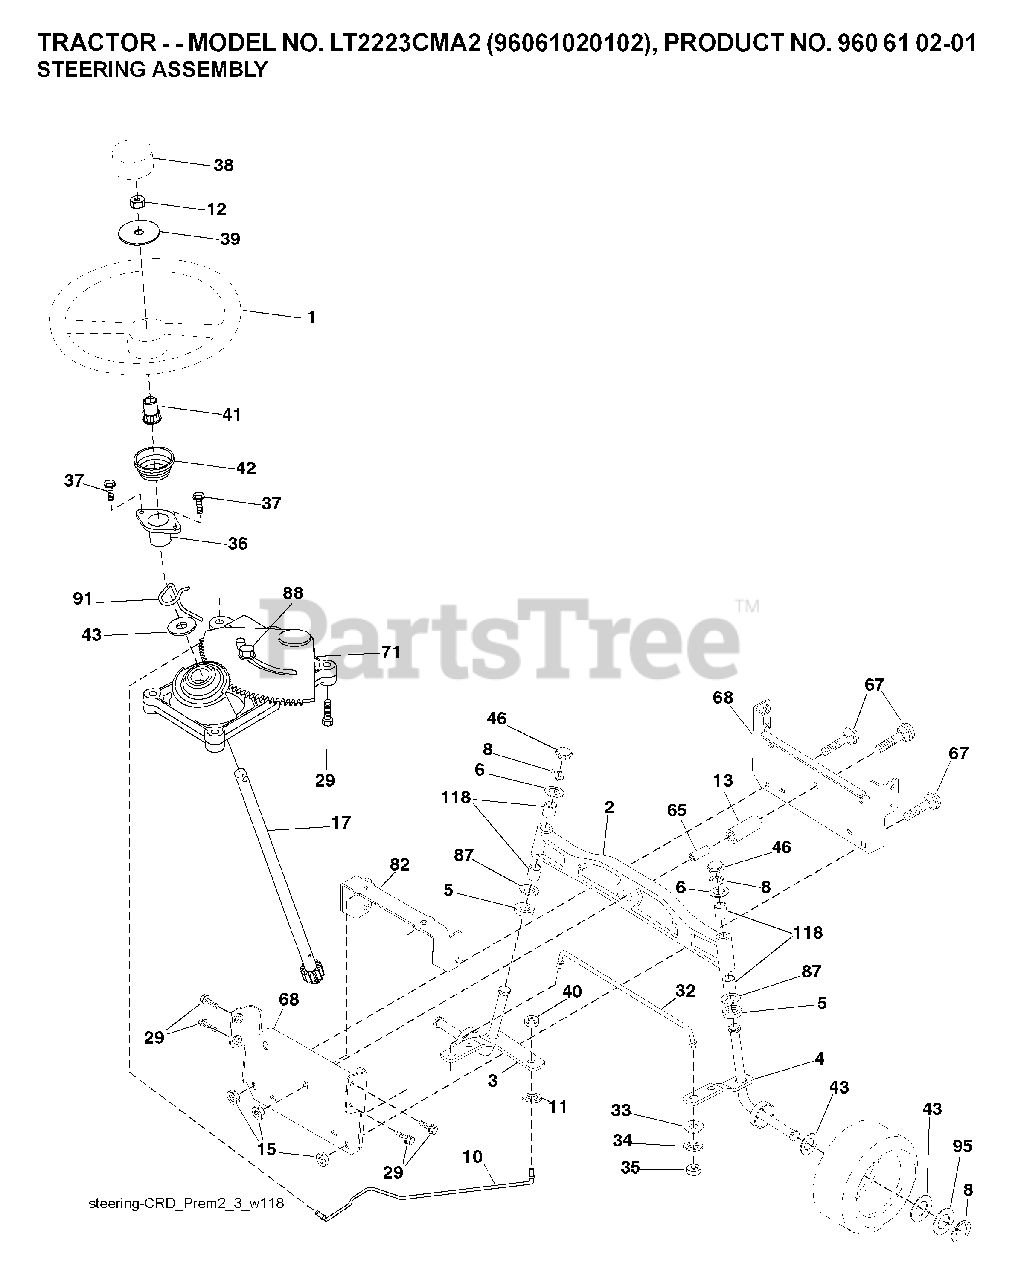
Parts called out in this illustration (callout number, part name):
1	WHEEL.STEERING.PREM.2.BLK
2	AXLE ASSY FRONT
3	SPINDLE.ASM.LH.15"TIRES
4	SPINDLE.ASM.RH.15"TIRES
8	RING CLIP
10	DRAGLINK.15".TIRES.2001
11	WASHER, LOCK 3/8
12	NUT.HEX.1/2-20
13	TUBE, PIVOT AXLE
15	NUT
17	SHAFT ASM STRG
29	SCREW, 3/8-16X3/4
33	WASHER M
34	LOCKWASHER
35	NUT, CROWNLOCK
36	BUSHING, STRG. BLK
38	INSERT.CAP.STRG.WH.BLACK
39	WASHER 9/16"ID, 2 3/8"OD
40	NUT CROWNLOCK 3/8-24
41	ADAPTER, WHEEL STNG..
46	CAP.SPINDLE
65	SPACER BRACE AXLE
67	BOLT CARRIAGE
68	BRACE.AXLE.15"TIRES
71	STEERING ASM
82	BRACKET.SUSP.CHASSIS.FRONT.15
87	WASHER, FLAT .781 X 1 1/2"
88	BOLT, SHOULDER 7/16-20
91	CLIP.STEERING
95	WASHER.HARDENED
118	BUSHING, AXLE CAST
